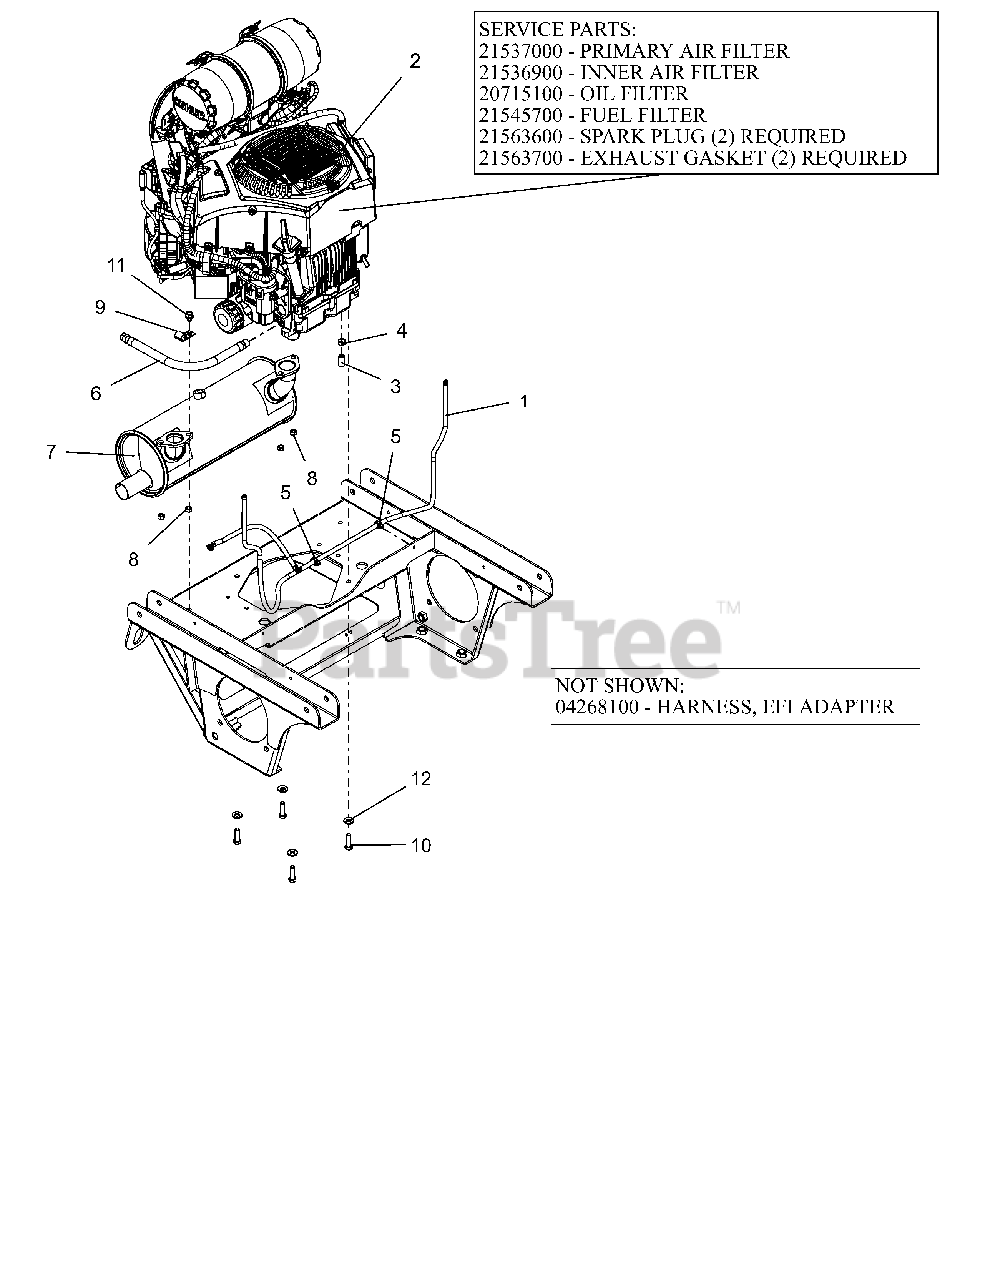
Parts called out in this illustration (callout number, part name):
1	ASM, KOHLER EFI VAPOR LINE
2	ENGINE, KOHLER ECV880-EFI
2	ELEMENT, OUTER PRIMARY
2	ELEMENT, INNER SAFETY
2	OIL FILTER KOHLER
2	FILTER-FUEL KOHLER COURAGE PRO
2	PLUG, SPARK
2	REGULATOR, EFI FUEL
3	HOSE, .25 LOW-PERM BULK GAS
4	CLAMP, FUEL LINE
5	ROUTING CLIP (1/2" ID)
6	HOSE, OIL DRAIN
7	MUFFLER, KOHLER EFI
8	NUT-LK-TOP M8-1.25 YWZC
10	BLT-HEX.38-16X1.25 G5YZ NYTORQ
11	@SCR-TAP .38-16X.50 HWH TR YWZ
12	WASHER, 3/8" SPRING DISC
